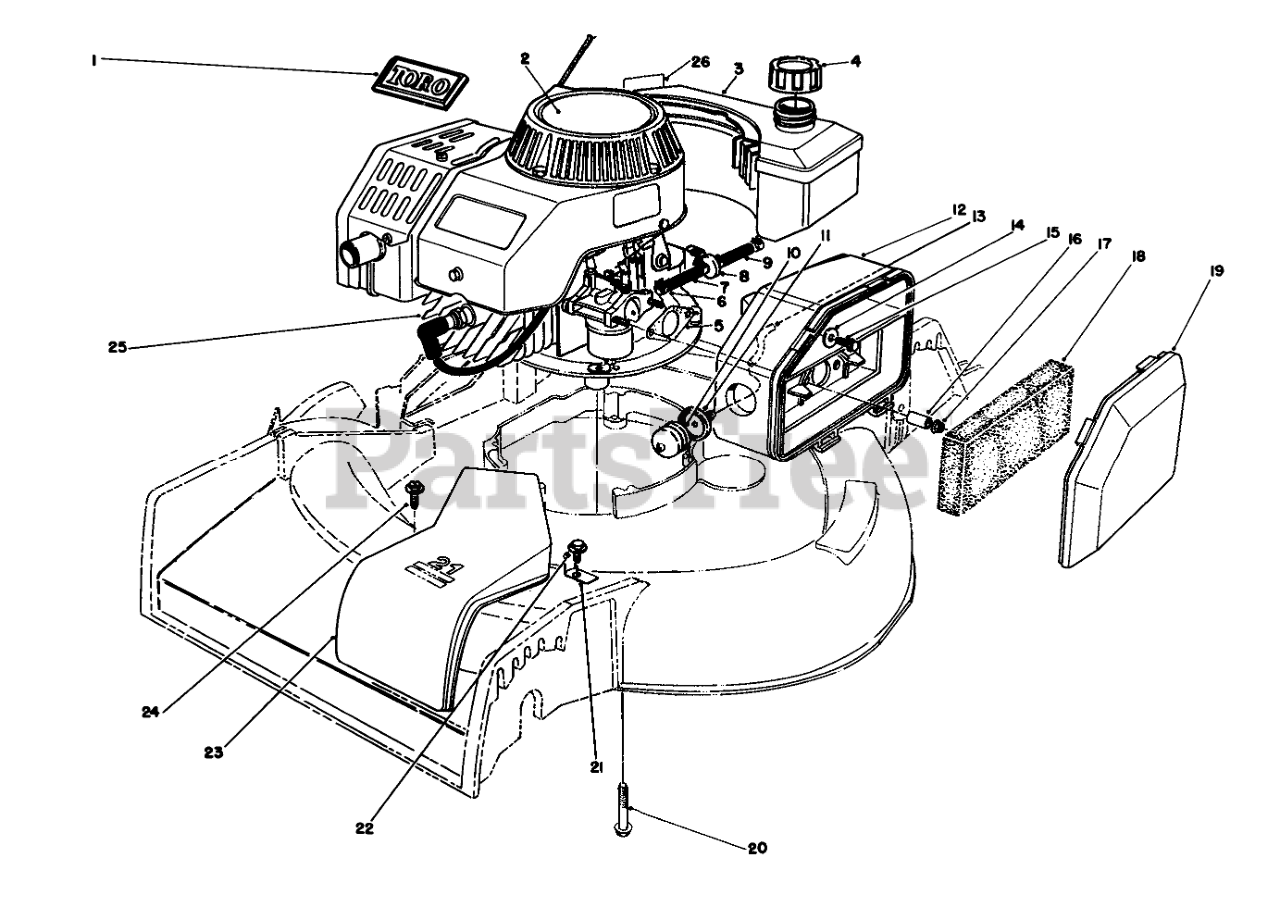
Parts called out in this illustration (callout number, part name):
1	TORO LOGO PLT
2	DECAL- 2 CYC RECOIL
3	FUEL TANK ASM
4	GAS CAP ASM
5	GASKET-AIR CLEANER
6	CLAMP-FUEL LINE
7	HOSE-FUEL
8	FILTER-FUEL
9	HOSE-FUEL
10	BULB-PRIMER
11	BODY-PRIMER
12	BODY-AIR CLEANER
13	HOSE-PRIMER
14	WASHER-FLAT
15	SCREW-HH
16	SPACER
18	ELEMENT-AIR CLEANER
19	COVER-AIR CLEANER
20	SCREW-HHF, WHIZ
21	BELT GUIDE
22	SCREW-HWHTF
23	BELT COVER 21" S D
24	SCREW
25	Engine
26	Decal-Maintenance
